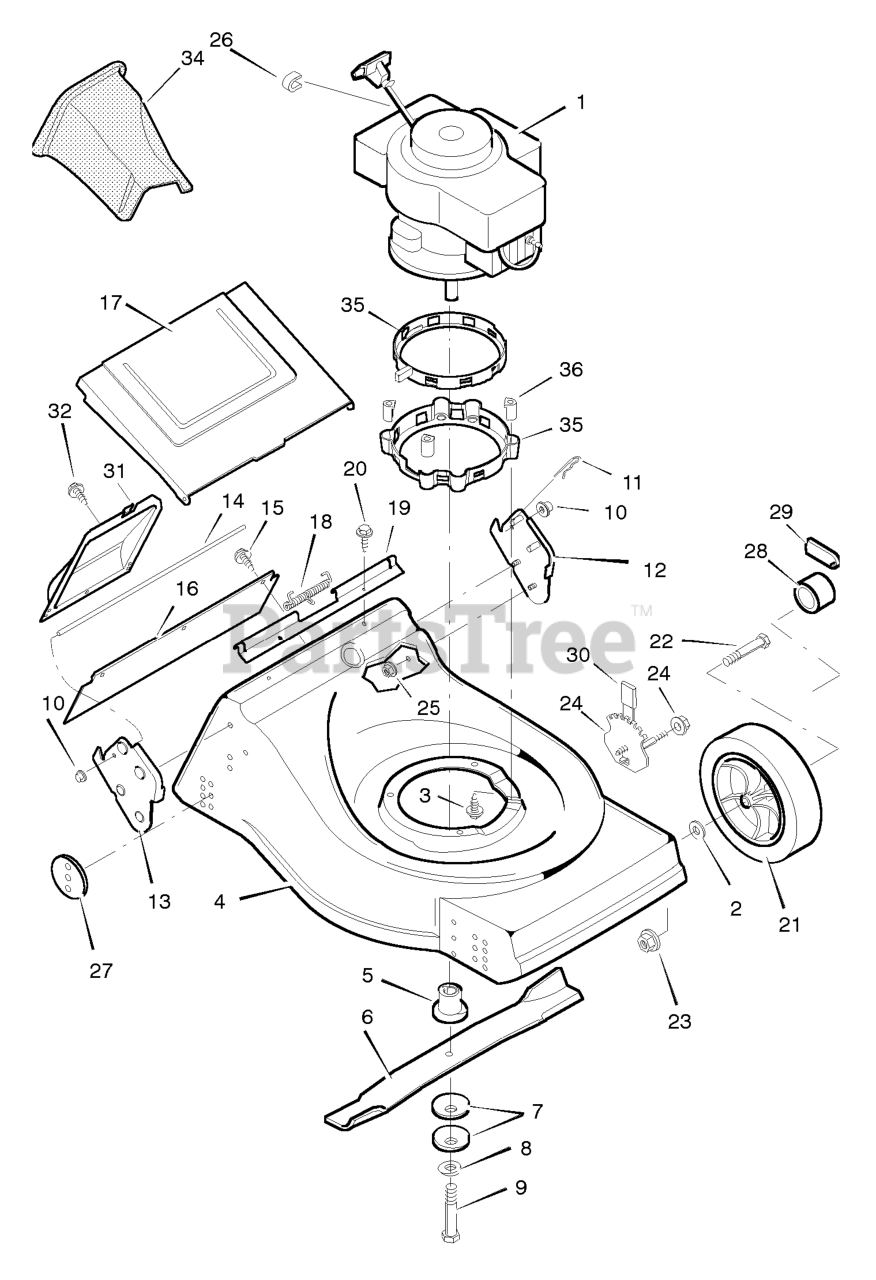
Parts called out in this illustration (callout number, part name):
1	Engine *
3	Bolt, Engine
4	Housing
5	Adapter, Blade
7	Washer, Belleville
9	Bolt, Hex
10	Push- On Cap
11	Pin, Hair
12	Bracket, Left Handle
13	Bracket, Right Handle
14	Rod, Door Pivot
16	Deflector, Rear (Model with Height Adjusters)
17	Door, Rear
18	Spring, Torsion
19	Spacer, Door
21	Wheel and Tire *
22	Bolt, Axle
23	Nut, Flange
24	Adjuster, Height
25	Nut, Flange
26	Stop, Rope
28	Hub Cap
29	Hub Cap
31	Cover, Transmission
34	Plug, Mulcher
35	Turbo Vent
36	Spacer, Turbo Vent
